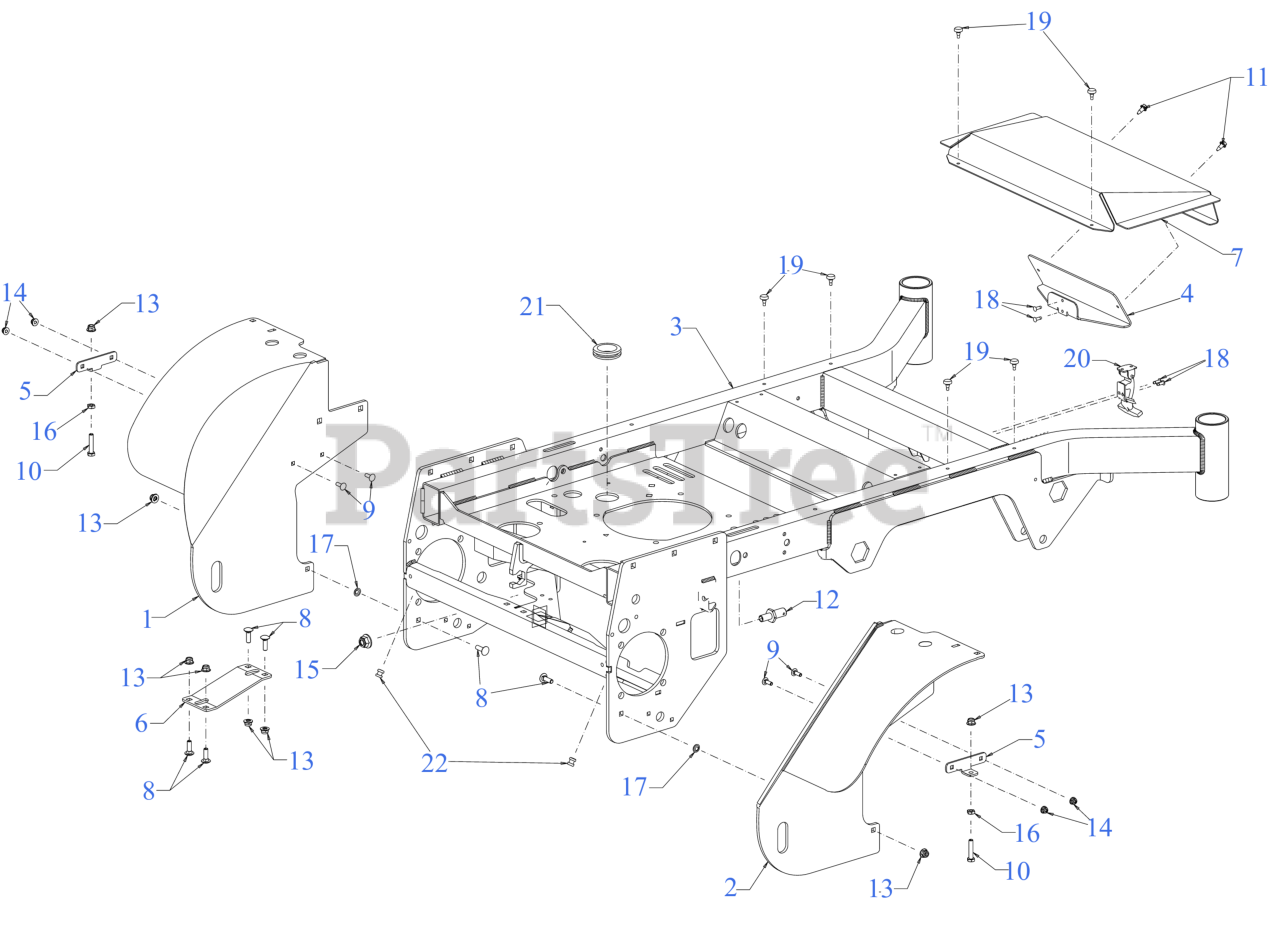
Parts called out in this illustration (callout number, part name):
1	FENDER (LH)
2	FENDER (RH)
4	BACK PLATE
5	BRAKE SPRING BRACKET (RH)
6	SUPPORT BRACKET
7	FRONT COVER
8	CARRIAGE BOLT 5/16-18 x 1.00
9	SCREW 1/4-20 x .75 GR5
10	SCREW 5/16-18 x 1.5 LG
11	SCREW 1/4-20X.625
13	FLANGE LOCK NUT 5/16-18
14	FLANGE LOCK NUT
16	HEX NUT
17	PUSH NUT
18	POP RIVET
19	RUBBER BUMPER
20	HOOD LATCH ASSEMBLY
21	RUBBER GROMMET (1.50X2.13X.563)
22	GROMMENT
